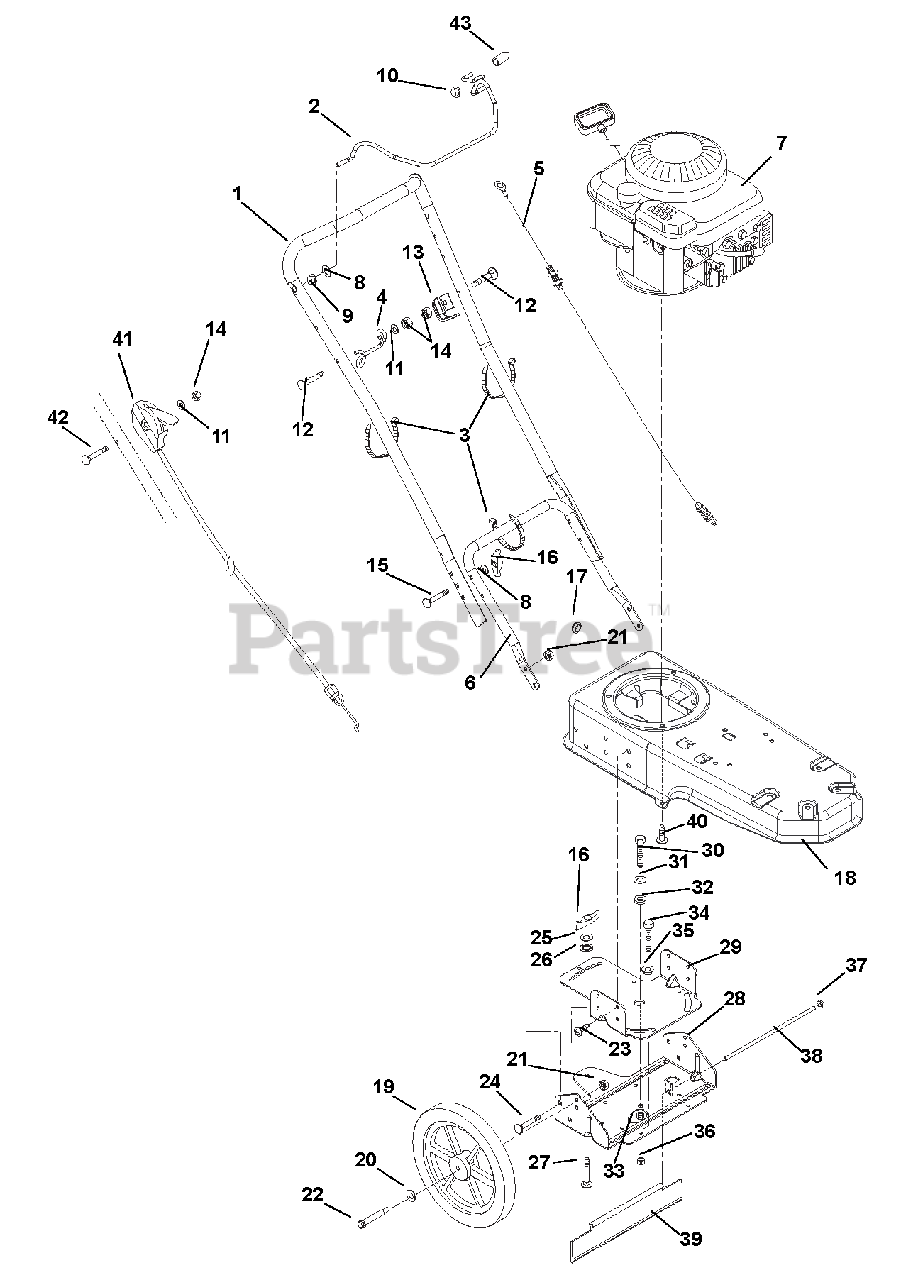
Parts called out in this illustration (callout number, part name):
1	HANDLEBAR - UPPER
2	BAIL SS LF
3	CABLE TIE LG 5-1/2
4	GUIDE - PULLCORD
5	CABLE - CONTROL
6	HANDLEBAR - LOWER
7	ENGINE, B&S 6.25HP CE
8	@WSHR-FL-STL.344X.688X.065YWZC
9	BSHG-FLG .325X.444X.440X.560
10	PUSH NUT, .25
11	@WSHR-FL-STL.281X.62X.065 YWZC
12	BLT-RDHDXLSQNK.25-20X1.25 G5ZC
13	ANCHOR - CABLE
14	@NUT-LK-CTR .25-20 YWZC
15	BLT-RDHDSQNKFT .31-18X2.0 G5YZ
16	KNOB,WING .31-18 UNC NYL/TALC
17	GROMMET .50 ID
18	FRAME - TRIMMER
19	WHEEL 14 X 1.75 X .50
20	WSHR-FL-STL .52X.827X.062 YWZC
21	@NUT-LK-CTR .38-16 YWZC
22	BLT-SHLDR .38-16X2.50 HWH G5
23	@SCR-TAP .38-16X.75 HWH TR YWZ
24	@BLT-RDHDSQNK .38-16X.75 G5YZ
25	@WSHR-FL-STL.38X.875X.083 YWZC
26	NUT-PUSH .312
27	@BLT-RDHDSQNK .31-18X1.00 G5YZ
28	BRACKET - AXLE - SWIVEL
29	BASE - SWIVEL
30	@BLT-HEX .50-13X1.00 GR5 YWZC
31	@WSHR-FL-STL.563X1.38X.109YWZC
32	SPACER .531 X 1.00 X .225
33	@NUT-LK-CTR .50-13 YWZC
34	@BLT-HEX .31-18X1.00 GR5 YWZC
35	BSHG-FLG .32X.500X.344X.880
36	@NUT-LK-CTR .31-18 YWZC
37	NUT-PUSH .312 DIA. PAL
39	GUARD - REAR - SWIVEL
40	@SCR-TAP .38-16X1.00 HWH TR YZ
41	CABLE, BRIGGS TRIMMER THROTTLE
42	BLT-RDHDXLSQNK .25-20X2.0 G5YZ
43	CAP, VINYL, .25 ID
